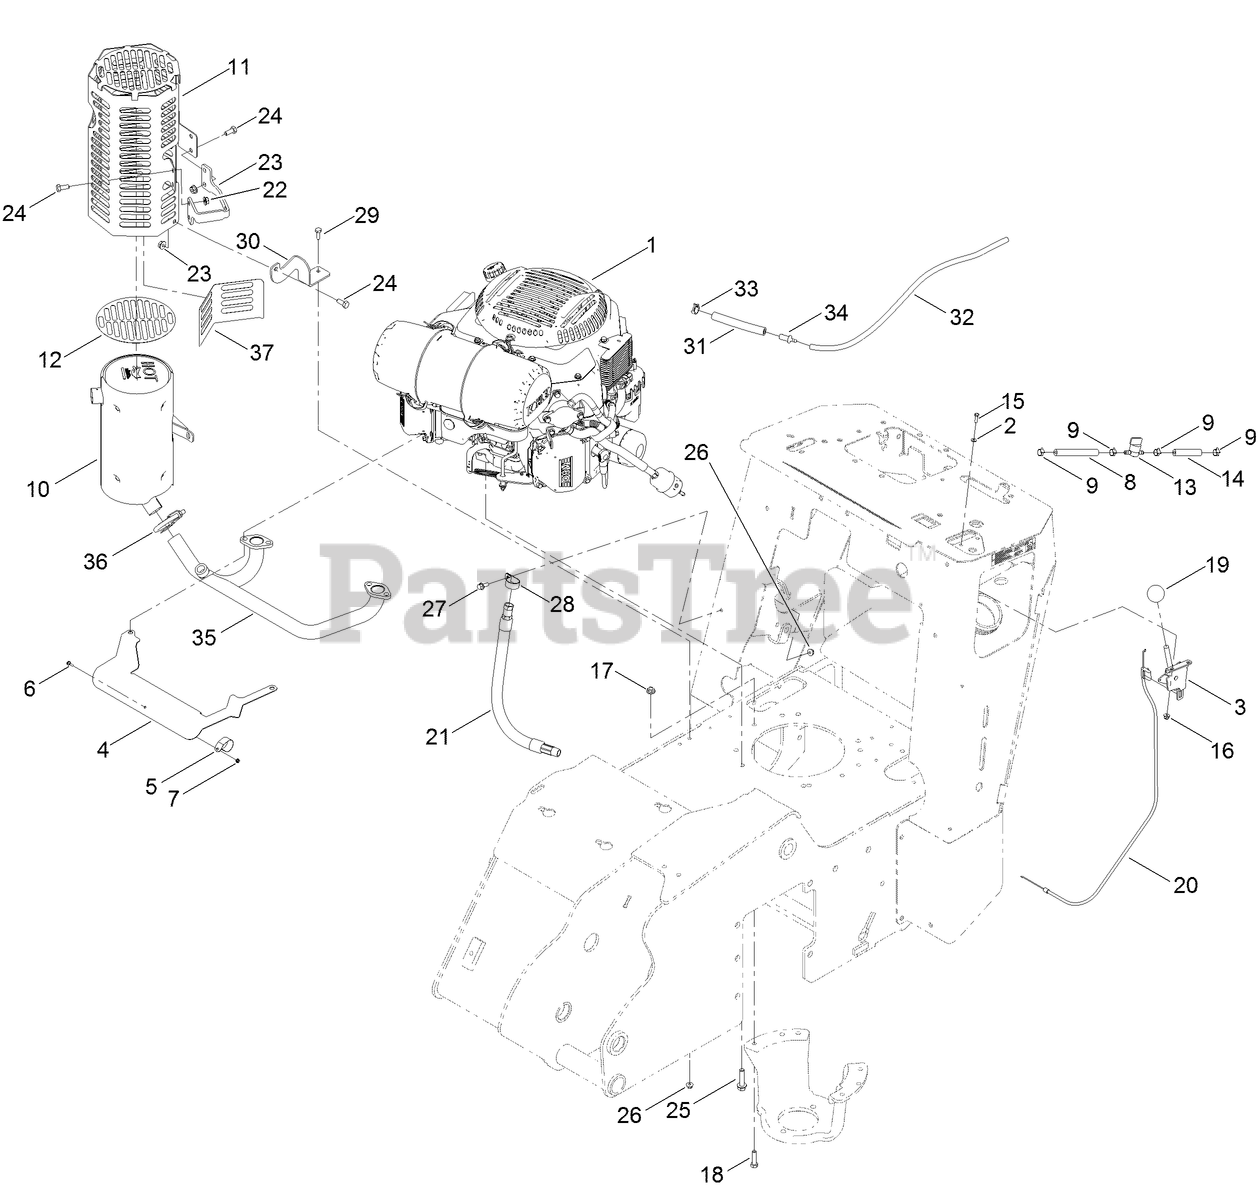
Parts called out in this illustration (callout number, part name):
1	ENGINE-KOHLER, PS-ECV749-3068
2	WASHER-FLAT
3	LEVER-CONTROL
4	SHIELD-HEAT
6	SCREW-PAN
7	NUT-HEX
8	HOSE-FUEL
9	CLAMP-HOSE
10	MUFFLER-KOHLER
11	GUARD-MUFFLER
12	FOIL-GUARD
13	VALVE-FUEL
14	HOSE-FUEL
16	NUT-HF
17	NUT-HF
18	SCREW-HH
20	CABLE-CONTROL
21	OIL DRAIN HOSE ASM
21:2	PLUG-HH
22	BRACKET-MUFFLER
23	NUT-FLANGE
24	SCREW-HH
25	SCREW-HWH
26	NUT-HF
27	SCREW-HHF
28	CLAMP-R
29	SCREW-HH
30	BRACKET-GUARD, MUFFLER
31	HOSE-VENT
32	HOSE-VENT
33	CLAMP-HOSE
34	FITTING-ORIFICE, STRAIGHT
35	MANIFOLD-KOHLER
36	CLAMP-MUFFLER
37	GUARD-FOIL
